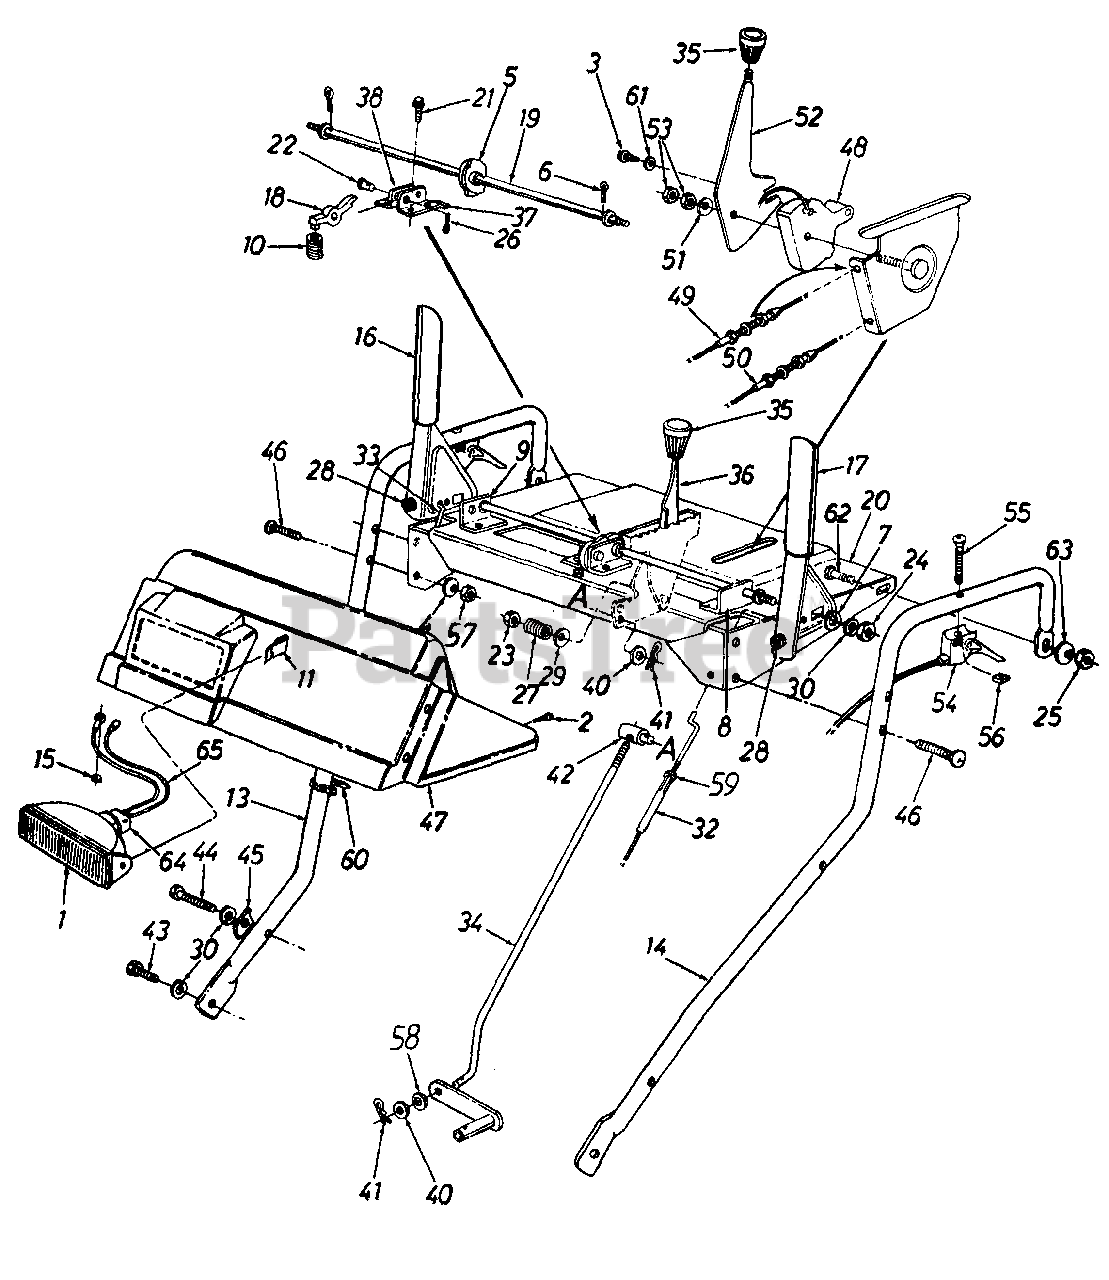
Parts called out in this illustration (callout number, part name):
1	Lamp Housing w/Lens
2	Truss Mach. B-Tap Scr. #10 x .5
3	Hex AB-Tap Scr. 1/4 x .62" Lg.
4	Bell-Wash. .325" I.D. x .88" O.D.
5	Cam Handle Lock
6	Cotter Pin 3/32" Dia. x .75" Lg.
7	Washer (Special) .72" O.D.
10	Compression Spring
11	Retaining Clip
13	Handle - R.H.
16	Engagement Handle - R.H.
17	Engagement Handle - L.H.
18	Pawl Handle Lock
22	Clevis Pin .437" Dia. x .65" Eg.
23	Hex Ins. L-Nut 3/8-24 Thd.
24	Hex Nut 5/16-18 Thd.
25	Hex Nut 1/4-20 Thd.
26	Cotter Pin 3/32" Dia. x 1" Lg.
27	Compression Spring
28	Rubber Bumper
29	Bell-Wash. .38" I.D. x .88" O.D.
30	L-Wash. 5/16" I.D.
32	Auger Clutch Cable
33	Drive Clutch Cable
34	Shift Rod
35	Shift Knob
36	Shift Handle
40	Fl-Wash. .344" I.D. x .62" O.D.
41	Internal Cotter Pin 5/16" Dia.
42	Ferrule
43	Hex Bolt 5/16-18 x .62" Lg. (Special)
44	Hex Bolt 5/16-18 x 1.75" Lg. (Gr. 5)
45	Handle Tab
46	Curved Carr. Bolt 5/16-18 x 1.5" Lg.
47	Handle Panel
48	Cable Guide
49	Chute Control Cable
50	Chute Control Cable w/Clip
51	Bell-Wash. .325" I.D. x .93" O.D.
53	Hex Cent. L-Nut 5/16-18 Thd.
54	Track Steer Cable w/Trigger
55	Oval C-Sunk Hd. Scr. 10-24 x 1.375" Lg.
56	Flat Weld Nut #10-24 Thd.
57	Hex Nut 5/16-18 Thd.
58	Spr. Wash. .32" I.D. x .62" O.D.
59	Hex Nut #10-24 Thd.
61	Washer (Special) 1.25" O.D.
62	Hex Bolt 1/4-20 x .85" Lg.
63	Bell-Wash. .265" I.D. x .75" O.D.
64	Bulb
65	Wire Harness
